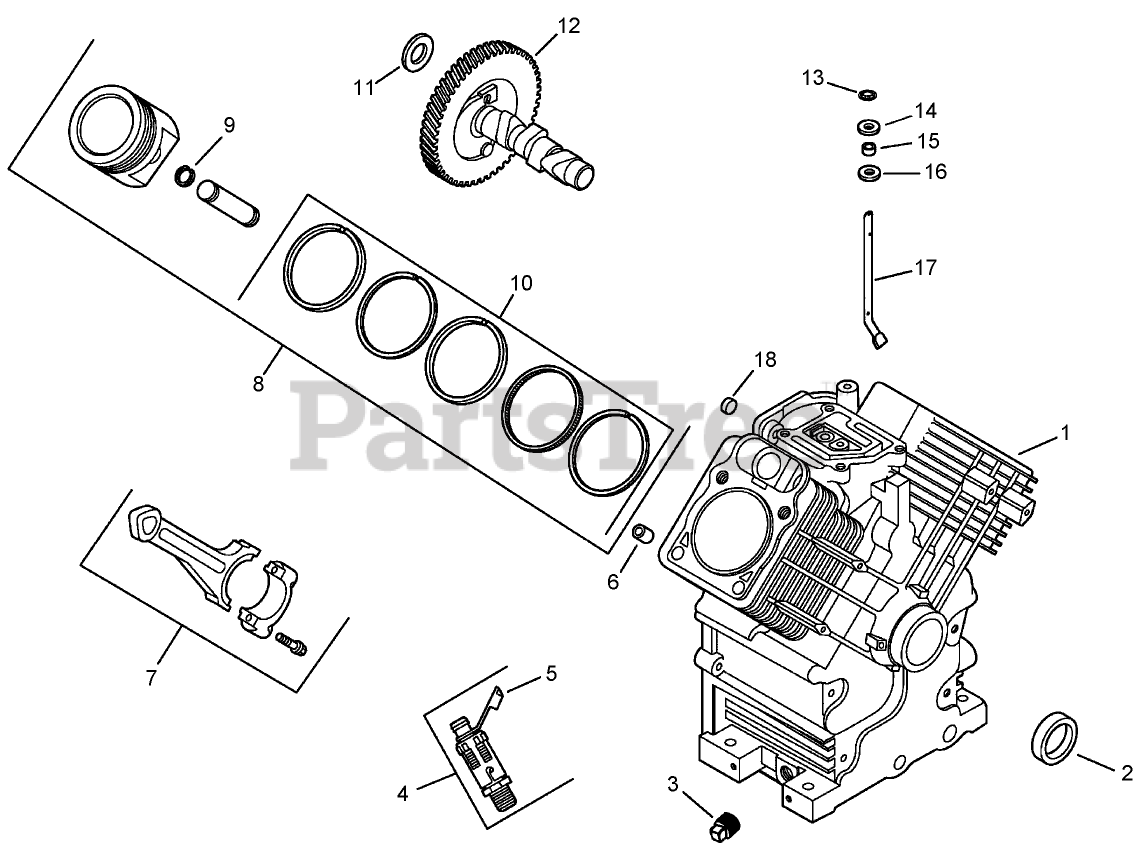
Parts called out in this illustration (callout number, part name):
2	SEAL-OIL
3	PLUG-PIPE, SQ HD (3/8)
4	Valve-Drain, Oil (Includes 5)
5	CAP-VALVE, OIL DRAIN
6	Pin-Locating
7	Rod-Connecting (Standard)
7	Rod-Connecting (.25)
8	Piston w/Ring Set (STD) (Includes 7, 8)
8	Piston and Ring Set (.08)
8	Piston and Ring Set (.25)
8	Piston and Ring Set (.50)
9	RETAINER-PIN, PISTON
10	Ring Set (.25)
10	Ring Set (.50)
11	SHIM-CAMSHAFT (YELLOW .034)
11	SHIM-CAMSHAFT (RED .032)
11	SHIM-CAMSHAFT (BLACK .04)
11	SHIM-CAMSHAFT (WHITE .028)
11	SHIM-CAMSHAFT (BLUE .03)
11	SHIM-CAMSHAFT (GREEN .036)
11	SHIM-CAMSHAFT (GRAY .038)
12	CAMSHAFT KIT
13	RETAINER-RING
14	WASHER-FLAT (9MM)
15	SEAL-CROSS SHAFT, GOVERNOR
16	WASHER-FLAT (11/32)
17	SHAFT-CROSS, GOVERNOR
18	PLUG-CUP
